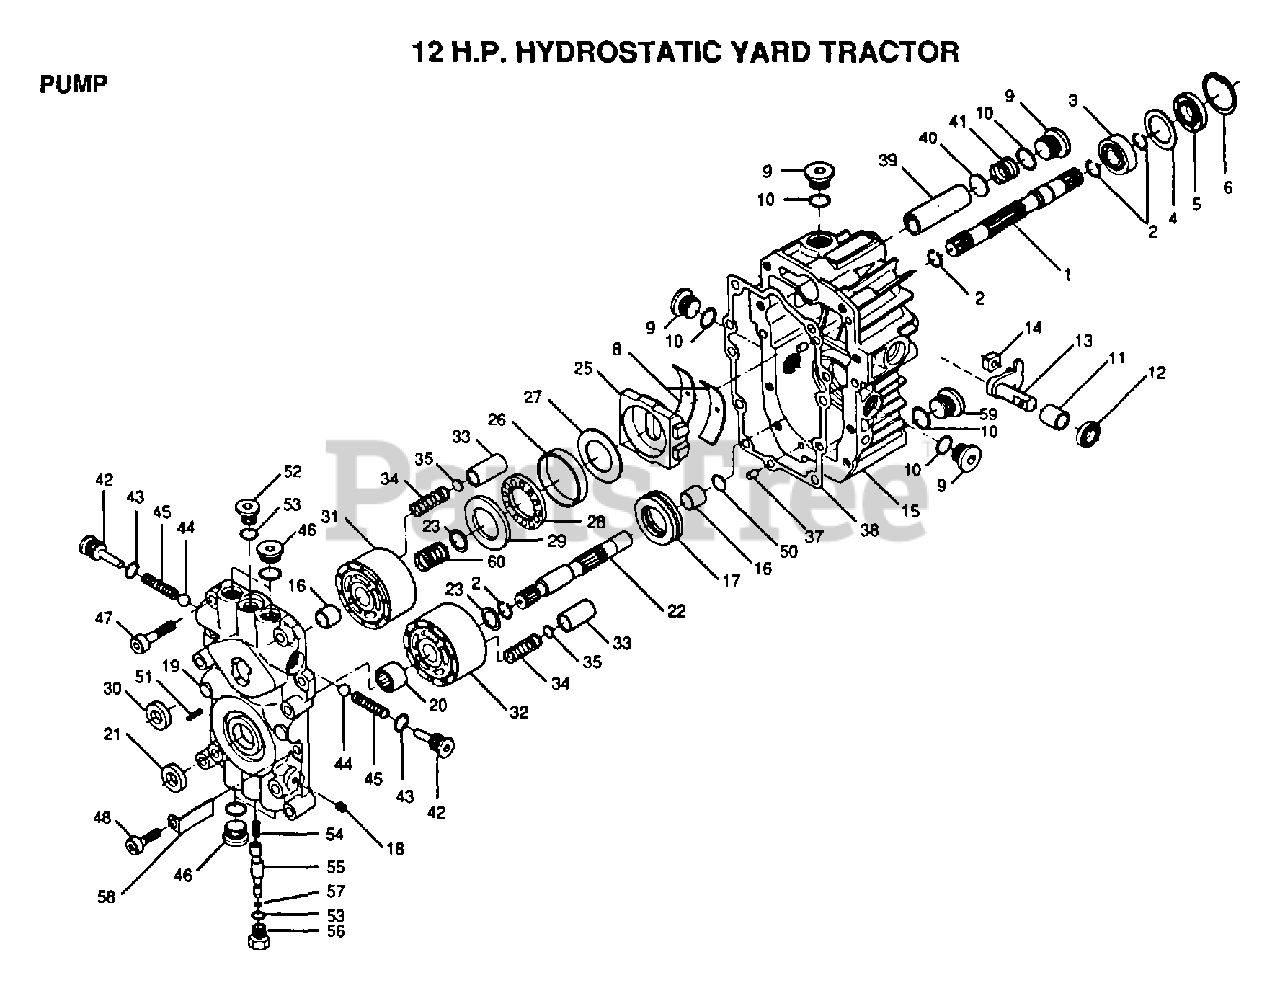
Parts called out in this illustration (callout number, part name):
1	SHAFT.PU.2003022
2	RETAINIANG RING-(2003016)
3	BALL BEARING
4	SPACER
5	SEAL LIP
6	RING.RET.2003052
8	CRADLE BEARING (2003023)
11	BEARING
12	SEAL.9008000-0126
13	TRUNION ARM (2003005)
14	GUIDE.2000015.HYD
17	JOURNAL BRG(2003071)
19	CENTER SECTION
20	NEEDLE BEARING
21	LIP SEAL-9008000-0127
22	SHAFT
23	WASHER
30	SEAL LIP
31	CYLINDER BLOCK
32	CYLINDER BLOCK(70331)
34	PISTON SPRING
35	WASHER.TR.2003019
37	PIN
38	GASKET.20030600
39	FILTER
40	WASHER (2000011)
41	SPRING
45	SPRING.2003012.HY
46	PLUG
47	SCREW9007314-0808
50	WASHER
51	PIN
52	PLUG
53	O RING
56	BYPAS KT 25130011
57	O RING (9004175-0027)
58	ADHESIVE LABEL
59	PLUG
